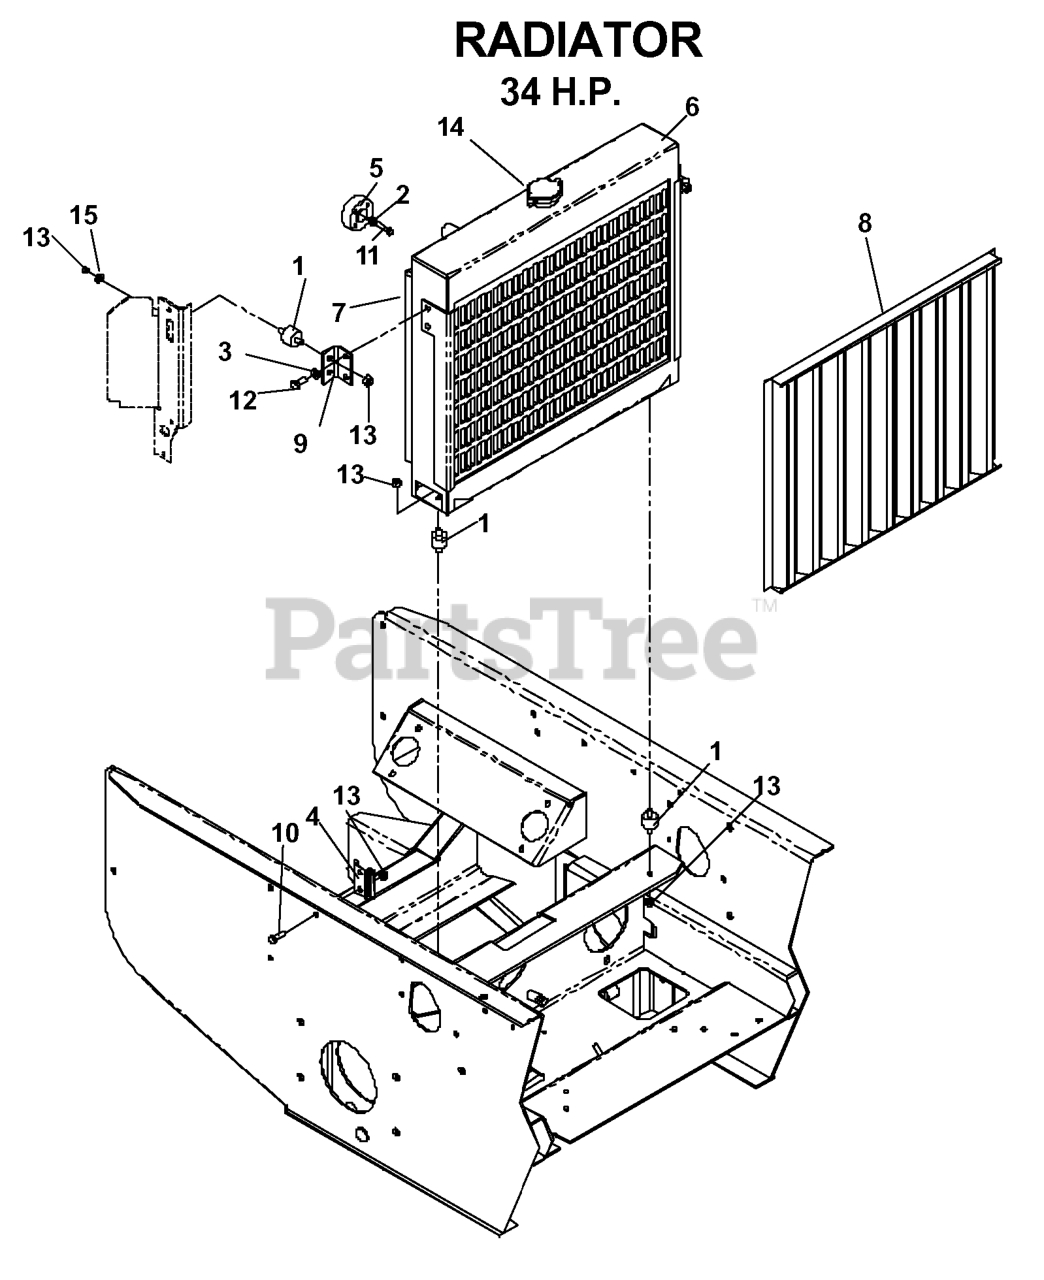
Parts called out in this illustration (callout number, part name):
2	LOCKWASHER 1/4"
3	WASHER.LOCK.HVY.HLCL.SPR.5/16
4	MOUNTING BRACKET
5	SPACER FAN
8	DEBRIS GUARD
9	BRACKET ISO
10	HCS 5/16C X 1
12	HCS 5/16C X 3/4
13	NUT 5/16 NYLOC
14	RADIATOR CAP
15	FLAT WASHER 5/16 SAE
539106326	LOWER HOSE
539106402	OVERFLOW TANK ASM
